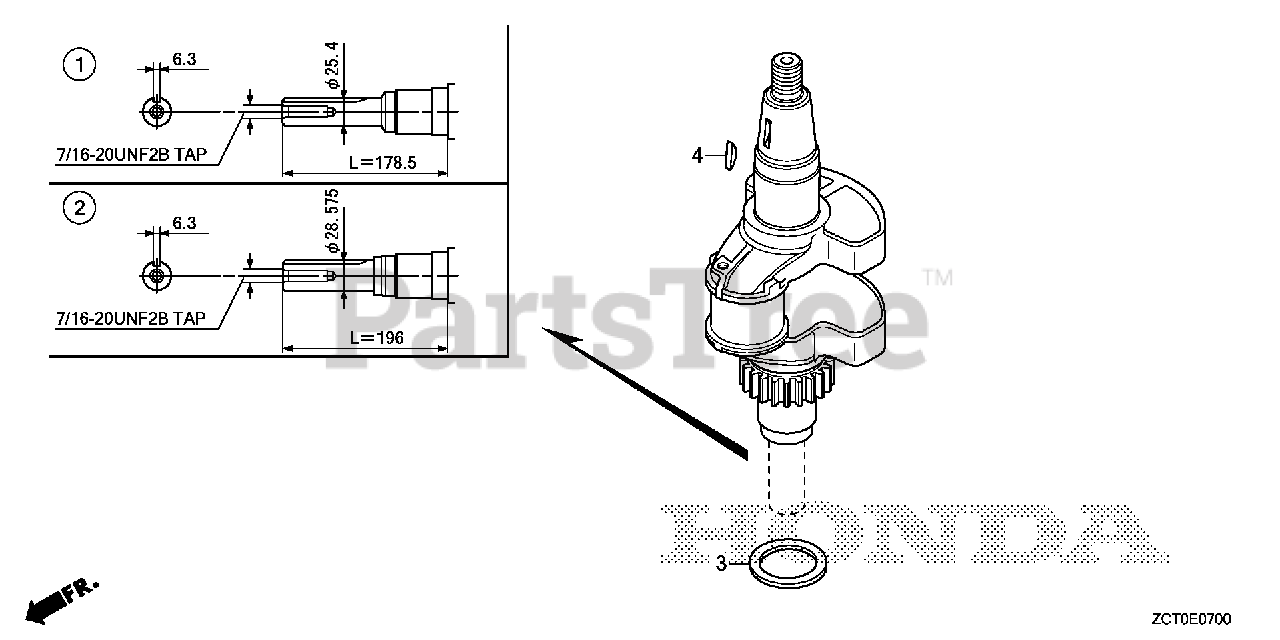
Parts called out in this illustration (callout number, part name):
2	CRANKSHAFT (L=196)
3	WASHER, CRANKSHAFT THRUST
4	KEY, SPECIAL WOODRUFF (25X18)
